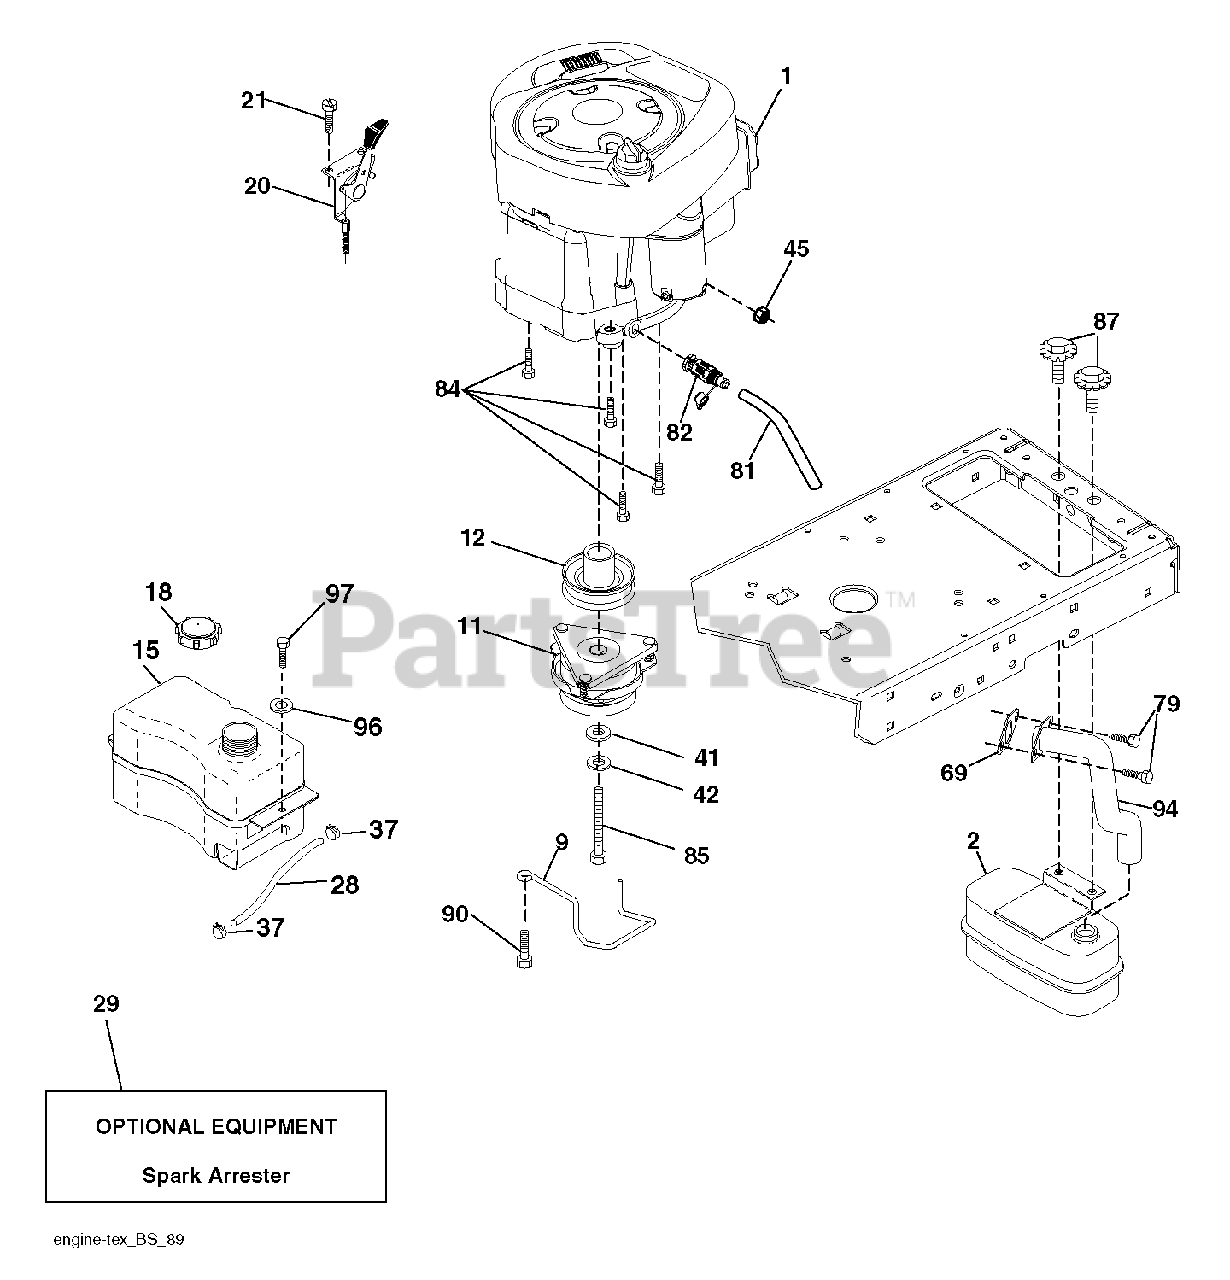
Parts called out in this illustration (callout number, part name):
2	MUFFLER.ASM.SNGL.XTNDED.DFLCTR
9	KEEPER.BELT.ENGINE.3.25 (3 2)
11	CLUTCH.ELECTRIC.LT.48"*
12	PULLEY.ENGINE.ENX
15	TANK.ASSEMBL.2.5GAL.NON-EPA
18	CAP ASM.FUEL.2.25"FR.
20	CONTROL.TH/CK.COBRA.KO
21	SCREW.#10 X 0.750.BOS
28	LINE.FUEL.20
29	KIT.SPARK ARRESTOR 794945 B&S
37	HOSE CLAMP
42	LOCKWASHER
45	NUT
69	REPL BY 532 27 22-93
79	SCREW.SOCKET HD.5/16-1
81	TUBE, DRAIN OIL ASM.
82	VALUE.OIL.DRAIN
84	SCREW.3/8-16
85	BOLT HEX 7/16-20X4-1/4"
87	Bolt, 5/16-18 X 1-3/4
90	SCREW 3/8-16X1
94	EXHAUST.TUBE.B&S.28/31
97	SCREW HEXWSHR 1/4-20X3/4
